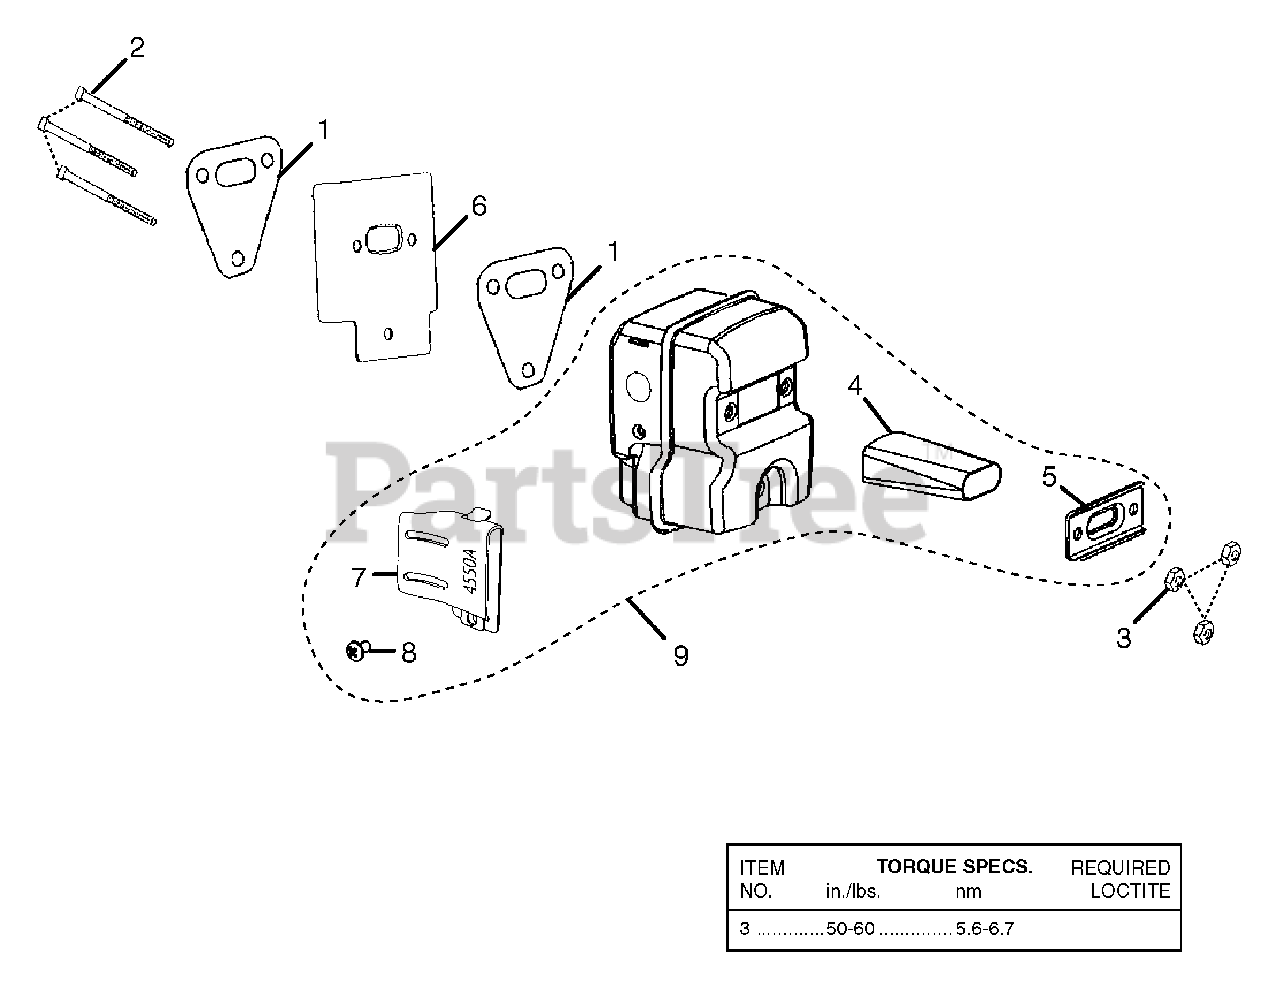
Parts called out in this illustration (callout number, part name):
1	MUFFLER GASKET
2	SCREW-SQUARE HD.
3	NUT-LOCKING HEX (10-32)
4	SCREEN, SPARK
5	SCREEN RETAINER
6	MUFFLER PLATE
7	DEFLECTOR, MUFFLER
8	SCREW (8-32 x .312 PAN HD.)
9	MUFFLER ASSEMBLY
